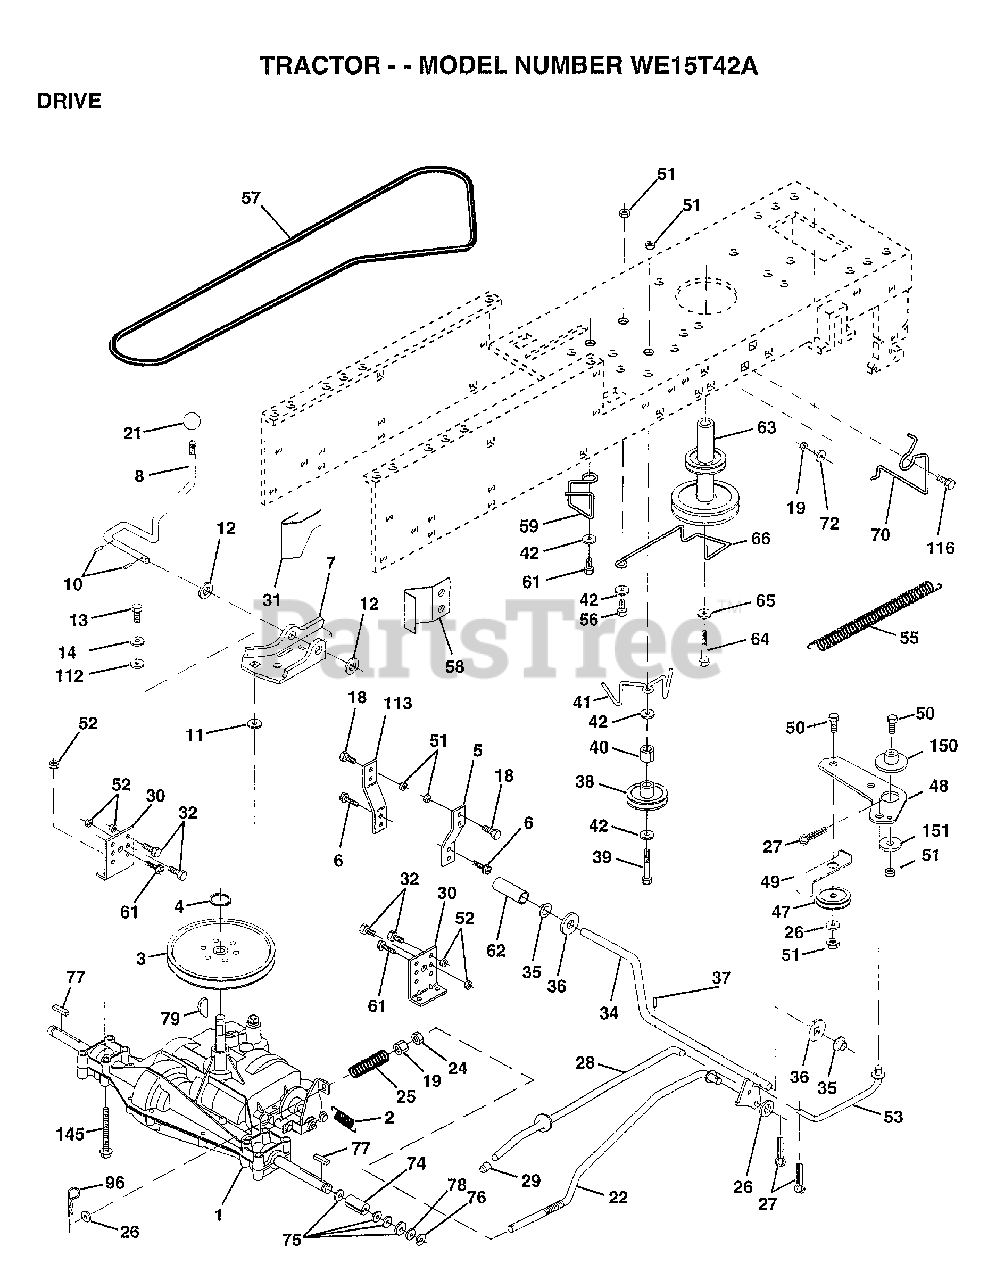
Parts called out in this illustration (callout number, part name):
3	PULLEY TRANS
5	STRAP TORQUE
6	SCREW
7	BRKT.SADDLE.SHIFT
8	SHIFT ROD
10	PIN COTTER 1/8
11	WASH-SHFT PLT LT
12	WASHER
13	BOLT.1/4-28.W/PAT
14	LOCKWASHER
18	BOLT
19	NUT
21	KNOB T (1/2-HOLE)
22	BRAKE ROD
24	NUT
25	SPRING ROD LT
26	WASHER
27	COTTER PIN
28	ROD.BRAKE.PARK.LT
29	PLUNGER CAP T
30	TRANSAXLE MTG BKT
31	"KEEPER,BELT LH T"
32	BOLT
34	SHAFT ASM-PEDAL F
35	NYLON BEARING
36	WASHER LT
38	FLAT IDLER PULLEY
39	BOLT
40	SPACER T
41	"KEEPER,BELT.IDLER FLAT"
42	WASHER
48	BELLCRANK.CLUTCH
49	RETAIN BELT
53	"LINK, CLUTCH T"
55	"SPRING, RETURN LT"
58	"KEEPER,BELT RH T"
59	KEEPER BELT CNTSP
61	SCREW
62	PEDAL COVER T
63	PULLEY.ENGINE
64	BOLT
65	LOCKWASHER
66	KEEPER-BELT
70	KEEPER BELT ENG
72	WASHER
74	SPACER AXLE
75	WASHER
76	E-RING LT
77	SQUARE KEY
78	WASHER
96	RETAINER M
112	WASHER LT
113	"STRAP,TORQUE"
116	BOLT RDHD 3/8-16
145	BOLT.HEX.FLGHD
150	BUSHING.BELLCRANK.GRD.DR
151	WASHER
